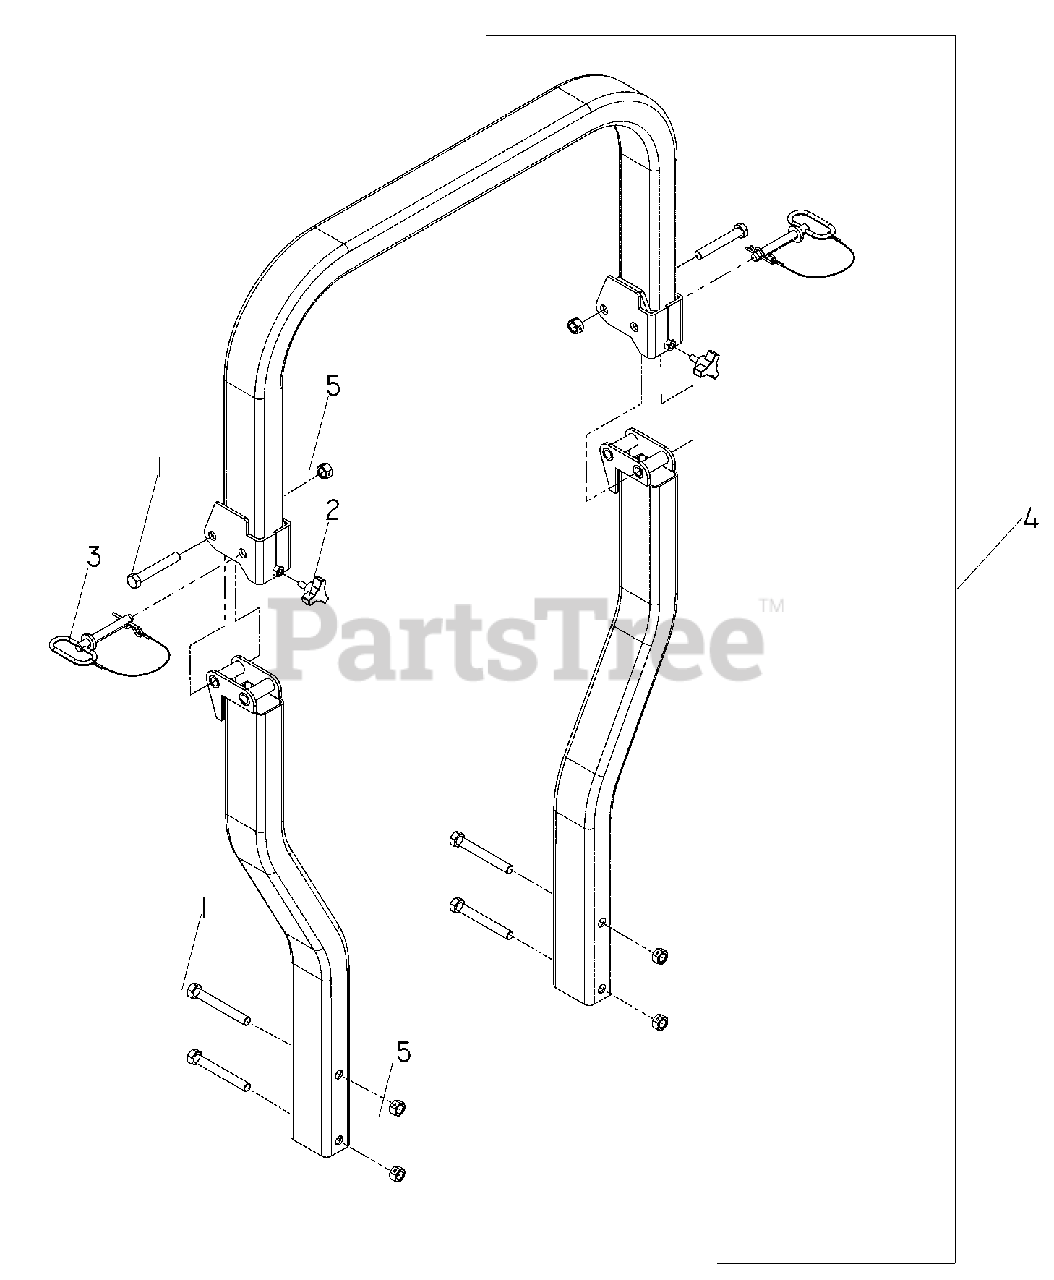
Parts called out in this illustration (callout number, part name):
1	HCS ½-13 x 3¼
2	KNOB W/ STUD
3	LANYARD W/PIN, ½"
4	ROPS, COMP W/SEAT BELT
5	NUT ½ -13, CENTERLOCK
